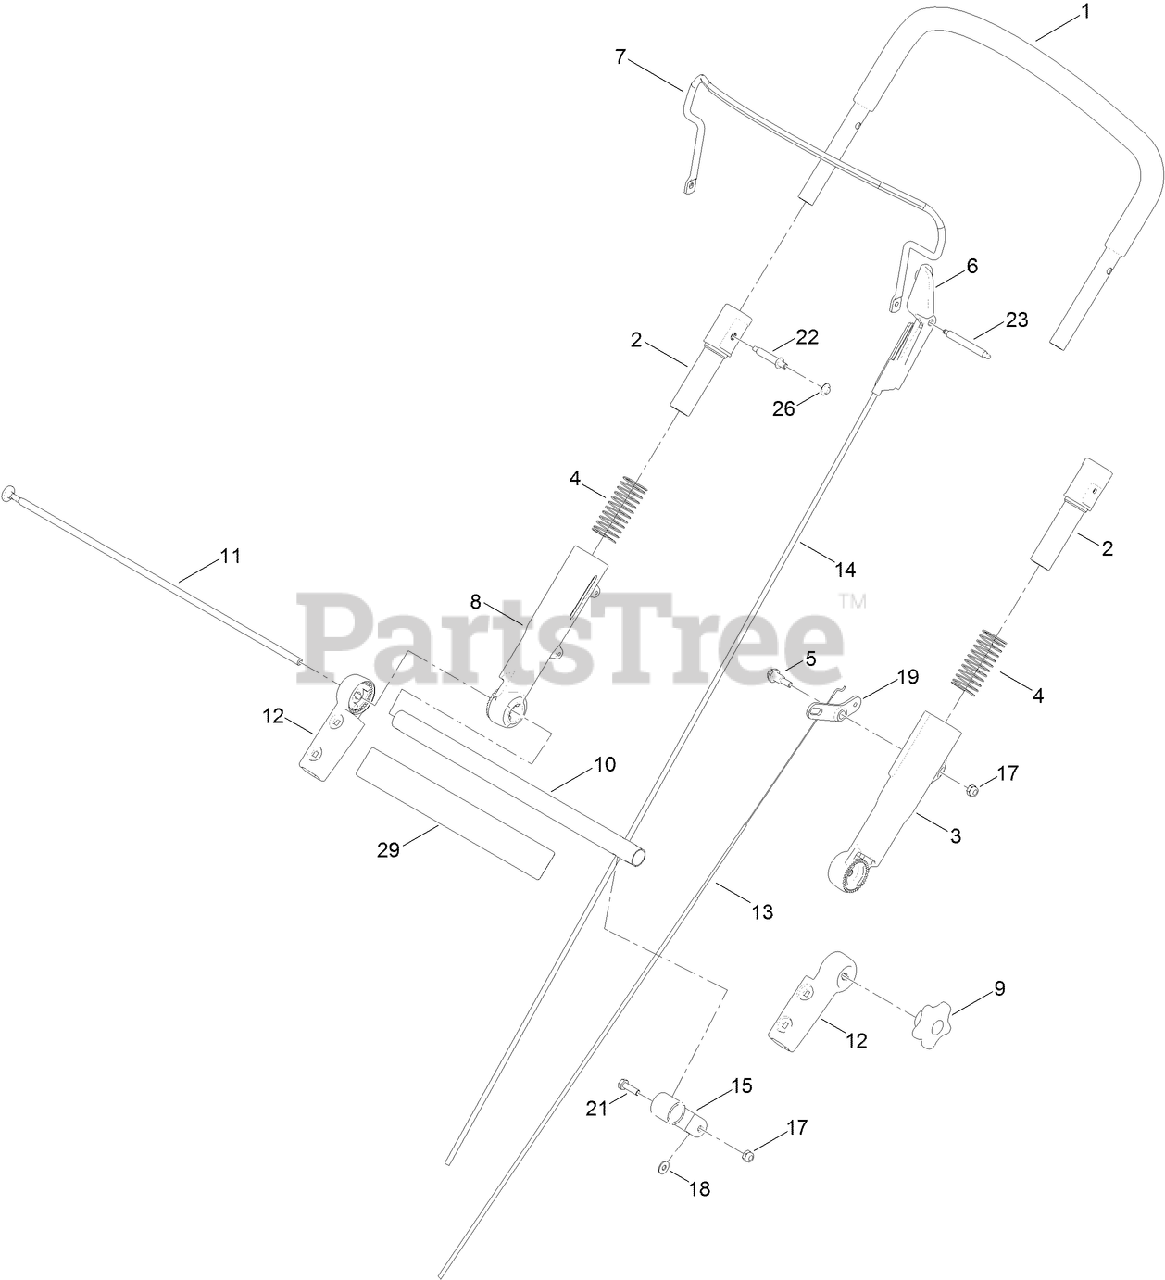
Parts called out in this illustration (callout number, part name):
1	UPPER HANDLE ASM
2	SLEEVE-INNER
3	SLEEVE-OUTER, LH
4	SPRING-COMPRESSION
5	BOLT-SHOULDER
6	STOP-PIVOT
7	BAIL-BRAKE
8	SLEEVE-OUTER, RH
9	KNOB-HANDLE
10	TUBE-CROSS
11	ROD-THREADED
12	MOUNT-HANDLE, LOWER
13	CABLE-TRACTION
14	CABLE-BRAKE
15	CLAMP-CABLE
17	NUT-LOCK, NI
18	WASHER-FLAT
19	LEVER-TRACTION
21	SCREW-HH
22	PIN-HANDLE
23	PIN-BAIL, LH
26	RETAINER-PUSH ON
29	DECAL-ADS
